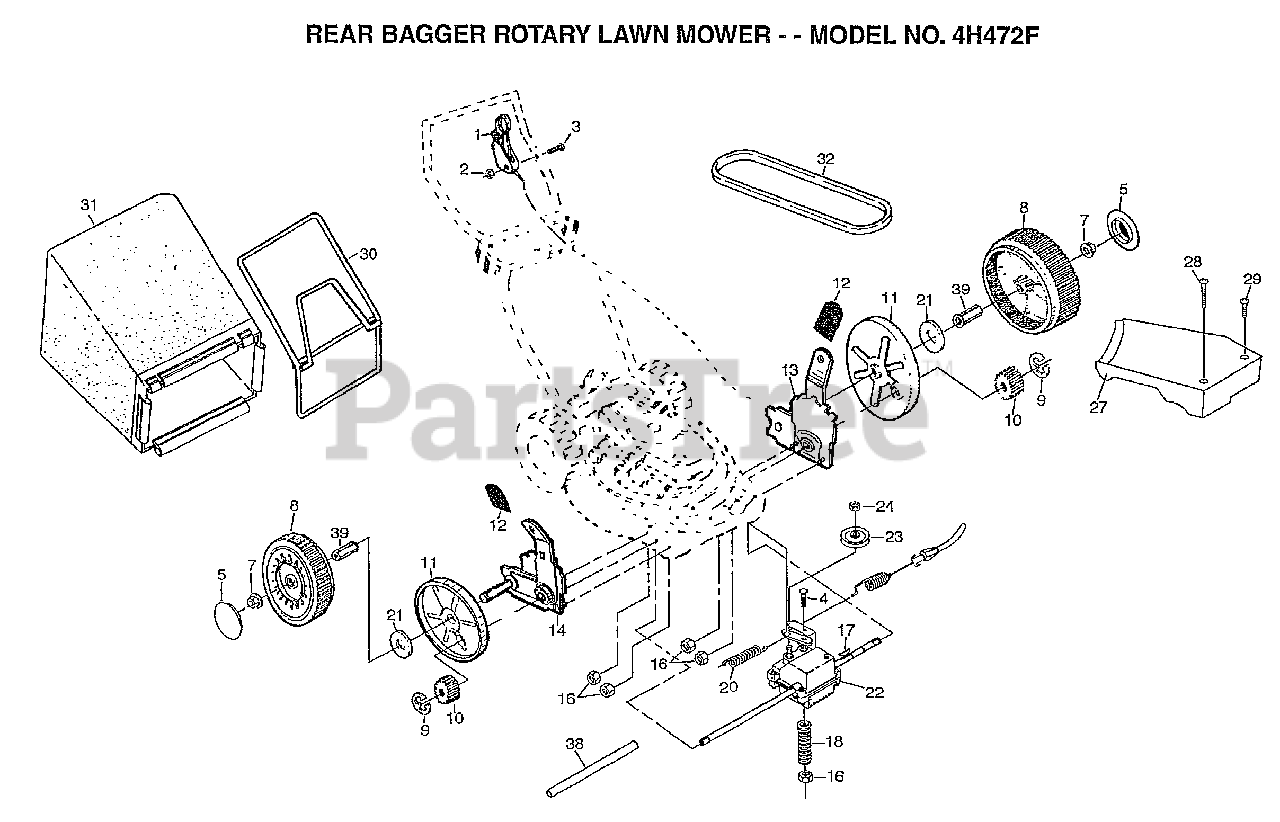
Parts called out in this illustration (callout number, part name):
1	CONTROL.DRV.56.25
3	SCREW.HXHD.WASH.
4	BOLT.1/4-20X2.0
5	HUB CAP
7	NUT.HXFLG.LOCK.
8	WHEEL.8X2.LP.PR
9	E-RING.7/16.RE.
10	PINION.GEAR
11	DUST SHROUD PM
12	KNOB PM
13	WHEEL.ADJ.ASM.LH.
14	WHEEL.ADJ.ASM.RH.
17	HI PRO KEY
18	SPRING.TENSION
20	SPRING
21	WASHER FLUT
23	PULLEY.DRIVEN
24	LOCKNUT
27	"COVER.DRIVE 22""RD"
28	SCREWL.SLOT.TORXT
29	SCREW.SLOT.TORTX.
30	FRAME.CATCHER.2.5
31	GRASSBAG.250B1.BL
38	DRV SHAFT TUBE PM
39	BUSHING.HEX
